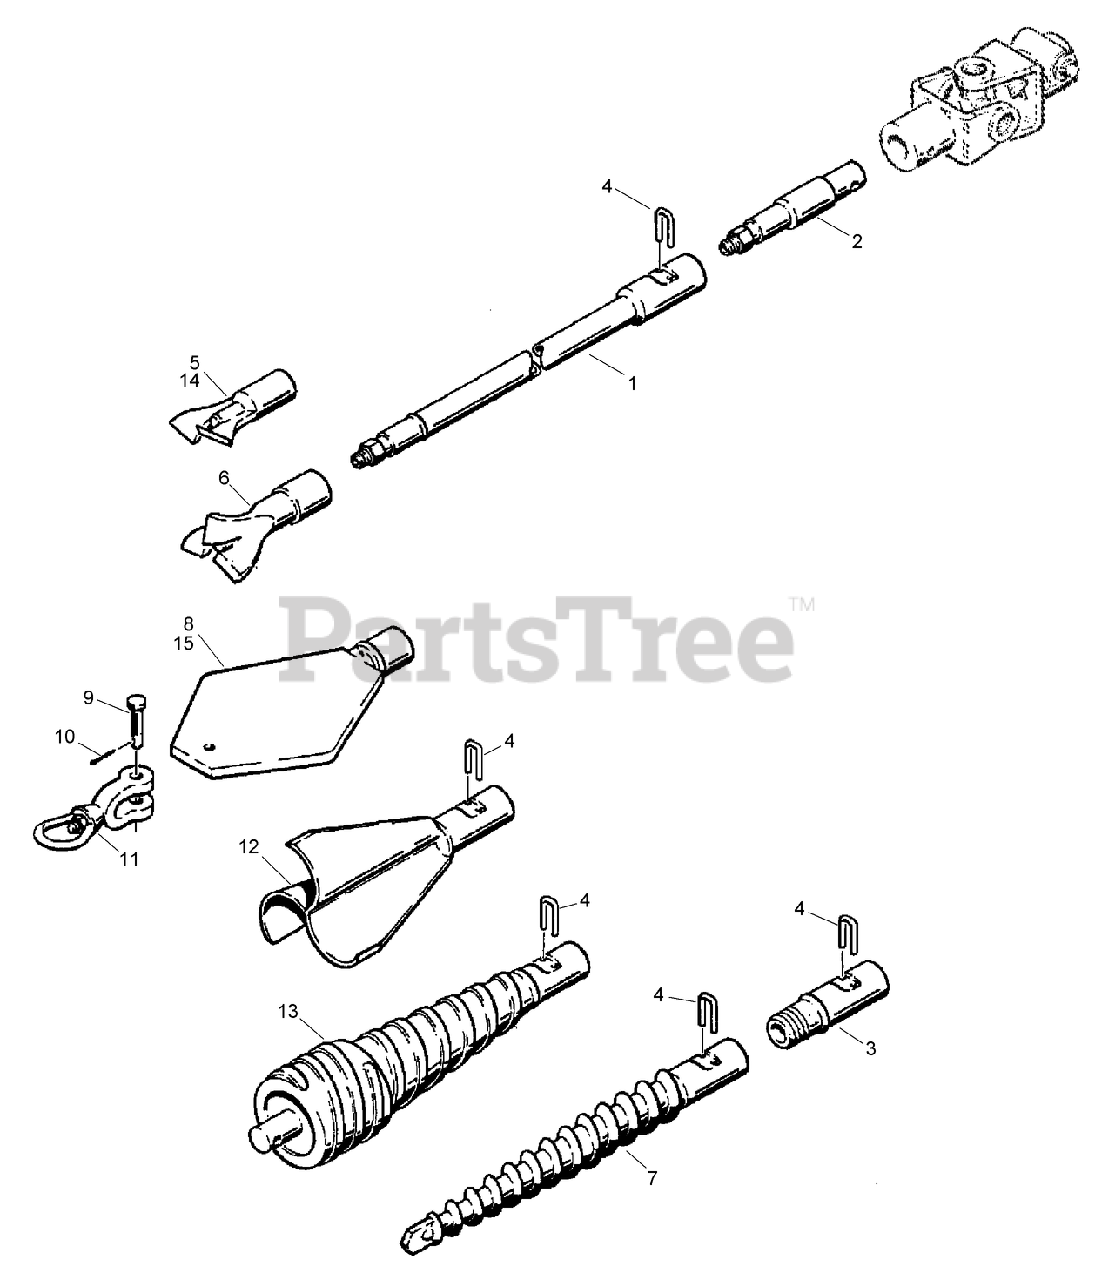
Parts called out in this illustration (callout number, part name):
1	STEM-Drill, Quick Lock, 10 ft Drill
2	ADAPTER-Quick Lock Male
3	COUPLER-1 in NPT to Female
4	CLIP-Retainer
5	BIT-Drill, Two Blade, 2 in Blade Dia x 1 in Female PT
6	BIT-Drill, Three Blade, 3 in Blade Dia x 1 in Female PT
7	MOLE-2 in Clip Type
8	REAMER-Fish Plate, 4 inch
8	REAMER-Fish Plate, 6 inch
8	REAMER-Fish Plate, 8 inch
9	PIN-Clevis, 3/8 x 1-3/4 inch long, Special
10	PIN-COTTER
11	SWIVEL-Reamer
12	BACKREAMER-Quick Lock Female, 8 inch
12	BACKREAMER-Quick Lock Female, 12 inch
13	REAMER-Compaction, Quick Lock Female, 3-3/4 inch
14	BIT-Drill, Two Blace, 3 in Bade Dia x 1 in Female PT
15	STEM-Drill, Quick Lock, 5 ft Drill
